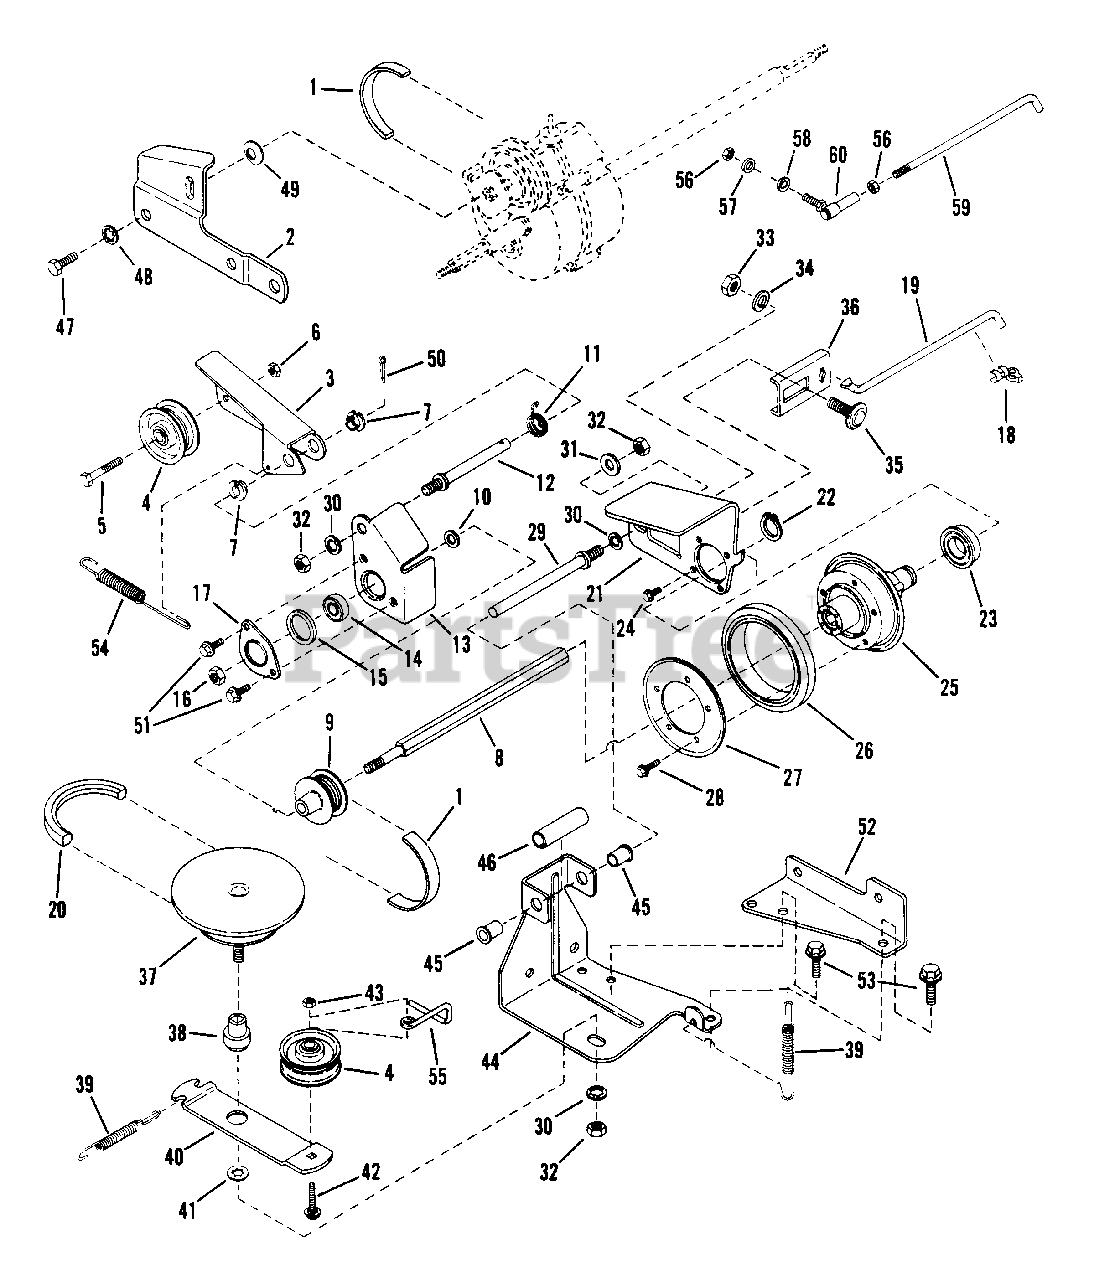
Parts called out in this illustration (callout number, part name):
1	BELT, Poly-Vee
2	LINK, Differential
3	ARM, Clutch Idler
4	PULLEY, Idler
5	SCREW, 1/4-28 x 1-3/8" Hex Head Cap
6	NUT, 1/4-28 Hex Lock
7	BUSHING, 3/8 I.D. Nylon
8	SHAFT, Hex
9	PULLEY, Poly-V
10	WASHER
11	SPRING, Torsion
12	STUD
13	HOLDER, Bearing (Inner Half)
14	BEARING, Ball
15	O-RING
16	NUT, 3/8 Hex Center Lock
17	HOLDER, Bearing (Outer Half)
18	CLIP, 1/4 Right Arc (Transfer Rod)
19	ROD, Transfer
20	BELT, Engine Drive
21	PLATE, Thrust
22	RING, Retaining
23	BEARING, Ball
24	SCREW, #10-32 x 1/4" Self-Tapping Machine
25	ASSEMBLY, Hub
26	RING, Driven
27	PLATE, Ring Retaining
28	SCREW, #10-24 x 1/2" Hex Washer Self-Tap (Torx)
29	GUIDE, Thrust Plate
30	WASHER, 3/8 Internal Tooth Lock
31	WASHER, 3/8" Flat
32	NUT, 3/8-24 Hex
33	NUT, 5/16-18 Hex
34	WASHER, 5/16 Split Lock
35	BOLT, 5/16-18 x 3/4" Carriage
36	CONNECTOR, Transfer Rod
37	ASSEMBLY, Drive Disc
38	BUSHING
39	SPRING (Wheel Drive & Idler)
40	ARM, Idler
41	RETAINER, 3/8 Bolt
42	BOLT, 1/4-20 x 1-3/8" Carriage
43	NUT, 1/4-20 Hex Center Lock
44	BRACKET, Deck
45	BUSHING, Flange
46	SPACER
47	SCREW, 5/16-18 x 1/2" Hex Head Cap
48	WASHER, 5/16 Internal Tooth Lock
49	WASHER, Spring
50	PIN, 3/32 x 1/2" Cotter
51	SCREW, 1/4-20 x 1/2" Self-Tapping
52	BRACKET, Strap
53	SCREW, 5/16-18 x 5/8" Self-Tapping
54	SPRING, Clutch
55	SCRAPER, Drive Pulley
56	NUT, 1/4-28 Hex
57	WASHER, 1/4 Flat
58	WASHER, 1/4 Internal Tooth Lock
59	JOINT, Ball
60	LINK, Transfer
